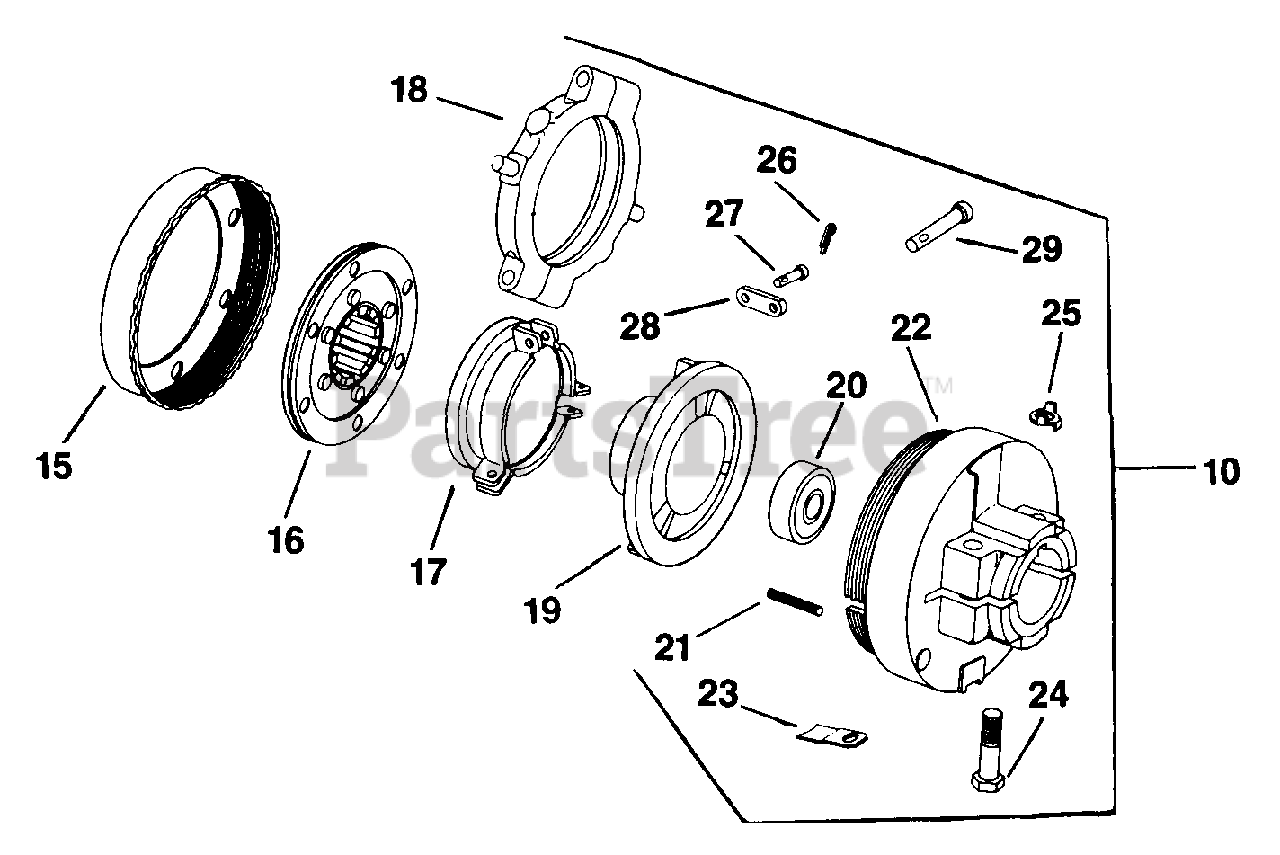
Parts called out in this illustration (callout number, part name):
17	SLEEVE - DISCONTINUED
18	BEARING - DISCONTINUED
19	PLATE - DISCONTINUED
20	Bearing
21	SPRING - DISCONTINUED
25	LOCK - DISCONTINUED
28	LINK - DISCONTINUED
